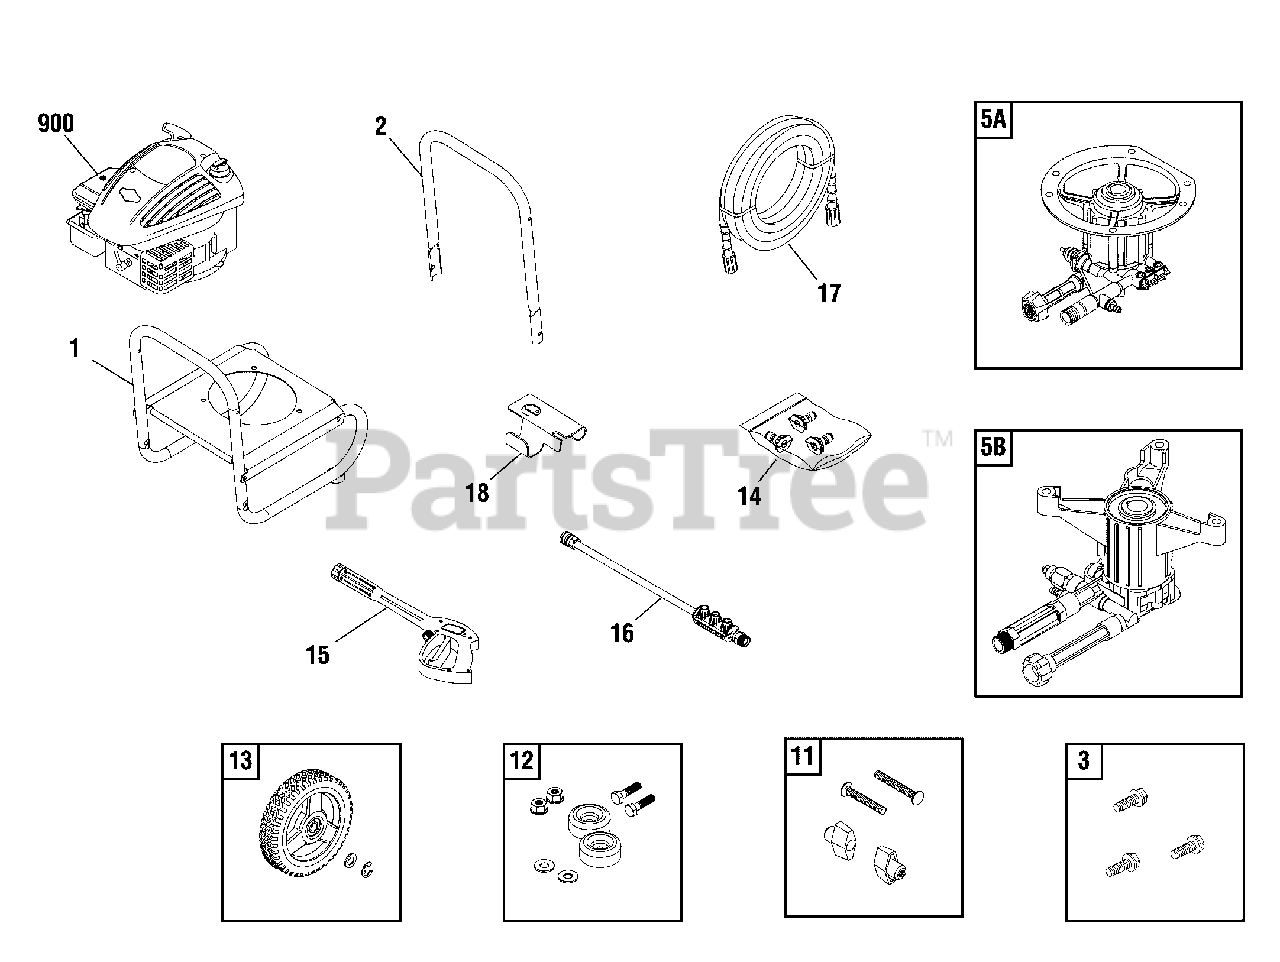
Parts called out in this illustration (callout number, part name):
2	HANDLE
3	KIT, Hardware, Engine Mounting
5A	PUMP
11	KIT, Hardware, Handle
12	MOUNT, Vibration
14	KIT, QC Nozzles
15	GUN
17	HOSE
900	* ENGINE
